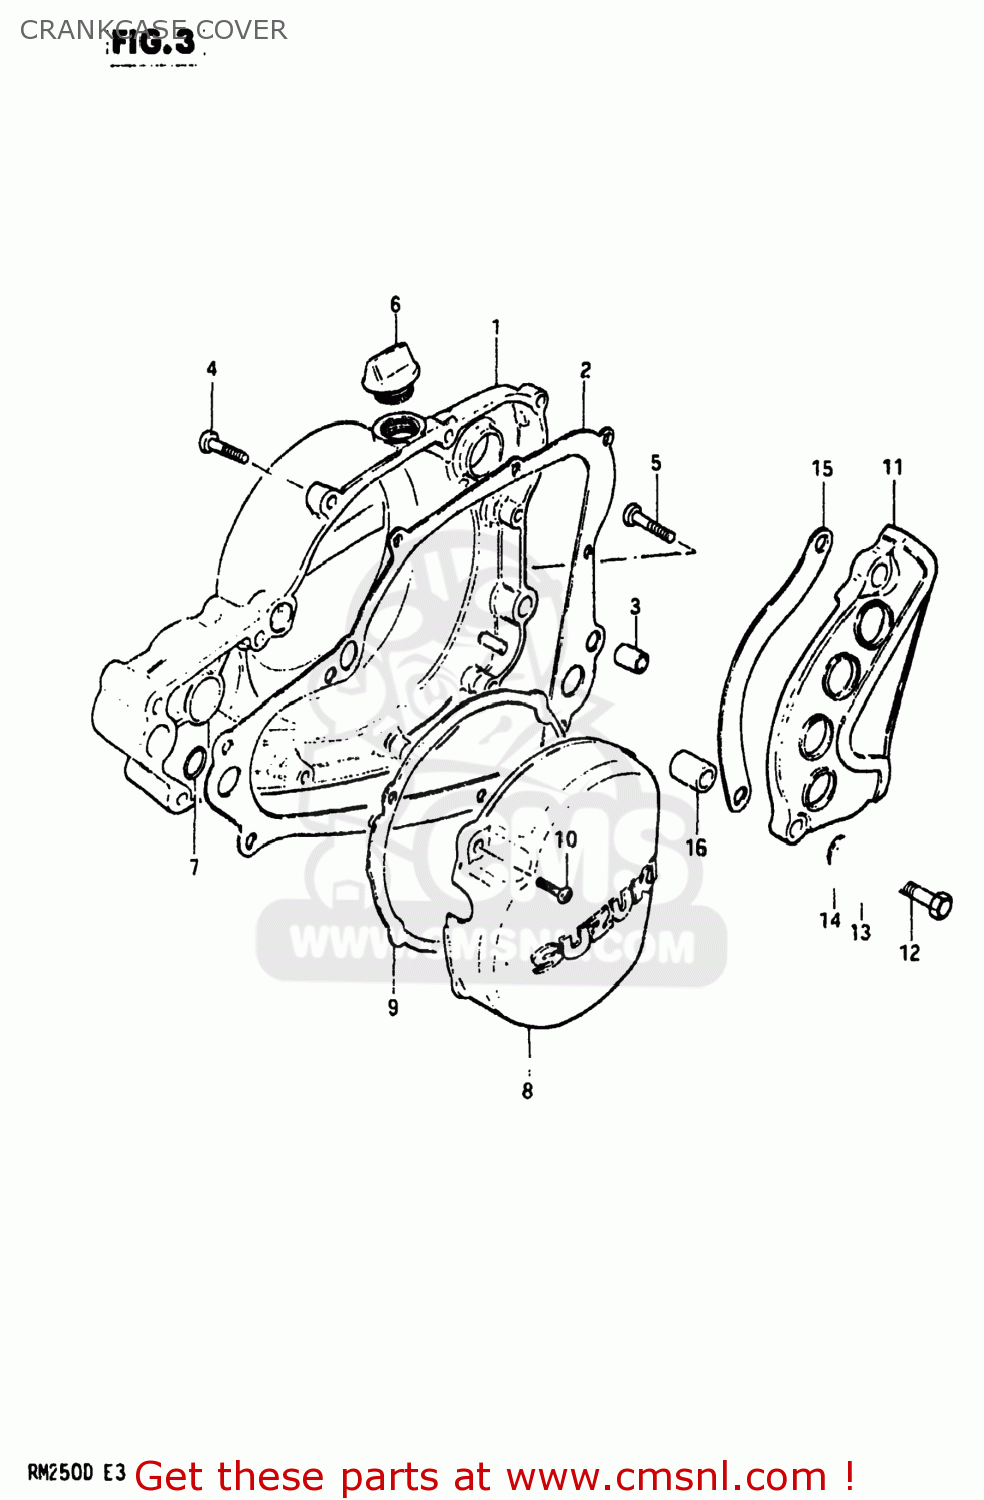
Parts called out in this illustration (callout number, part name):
1	COVER,CLUTCH
2	GASKET,CLUTCH COVER (MCA)
3	PIN
4	SCREW
5	SCREW
6	PLUG,OIL FILTER
7	O RING(D:2.4,ID:16.8)
8	COVER,MAGNETO
9	GASKET,MAGNETO COVER (MCA)
10	SCREW
11	COVER,ENGINE SPROCKET
12	BOLT 8X55
13	LOCK WASHER
14	WASHER,8.5X16X
15	PLATE,FR CHAIN GUIDE
16	SPACER(8.6X16X24)
